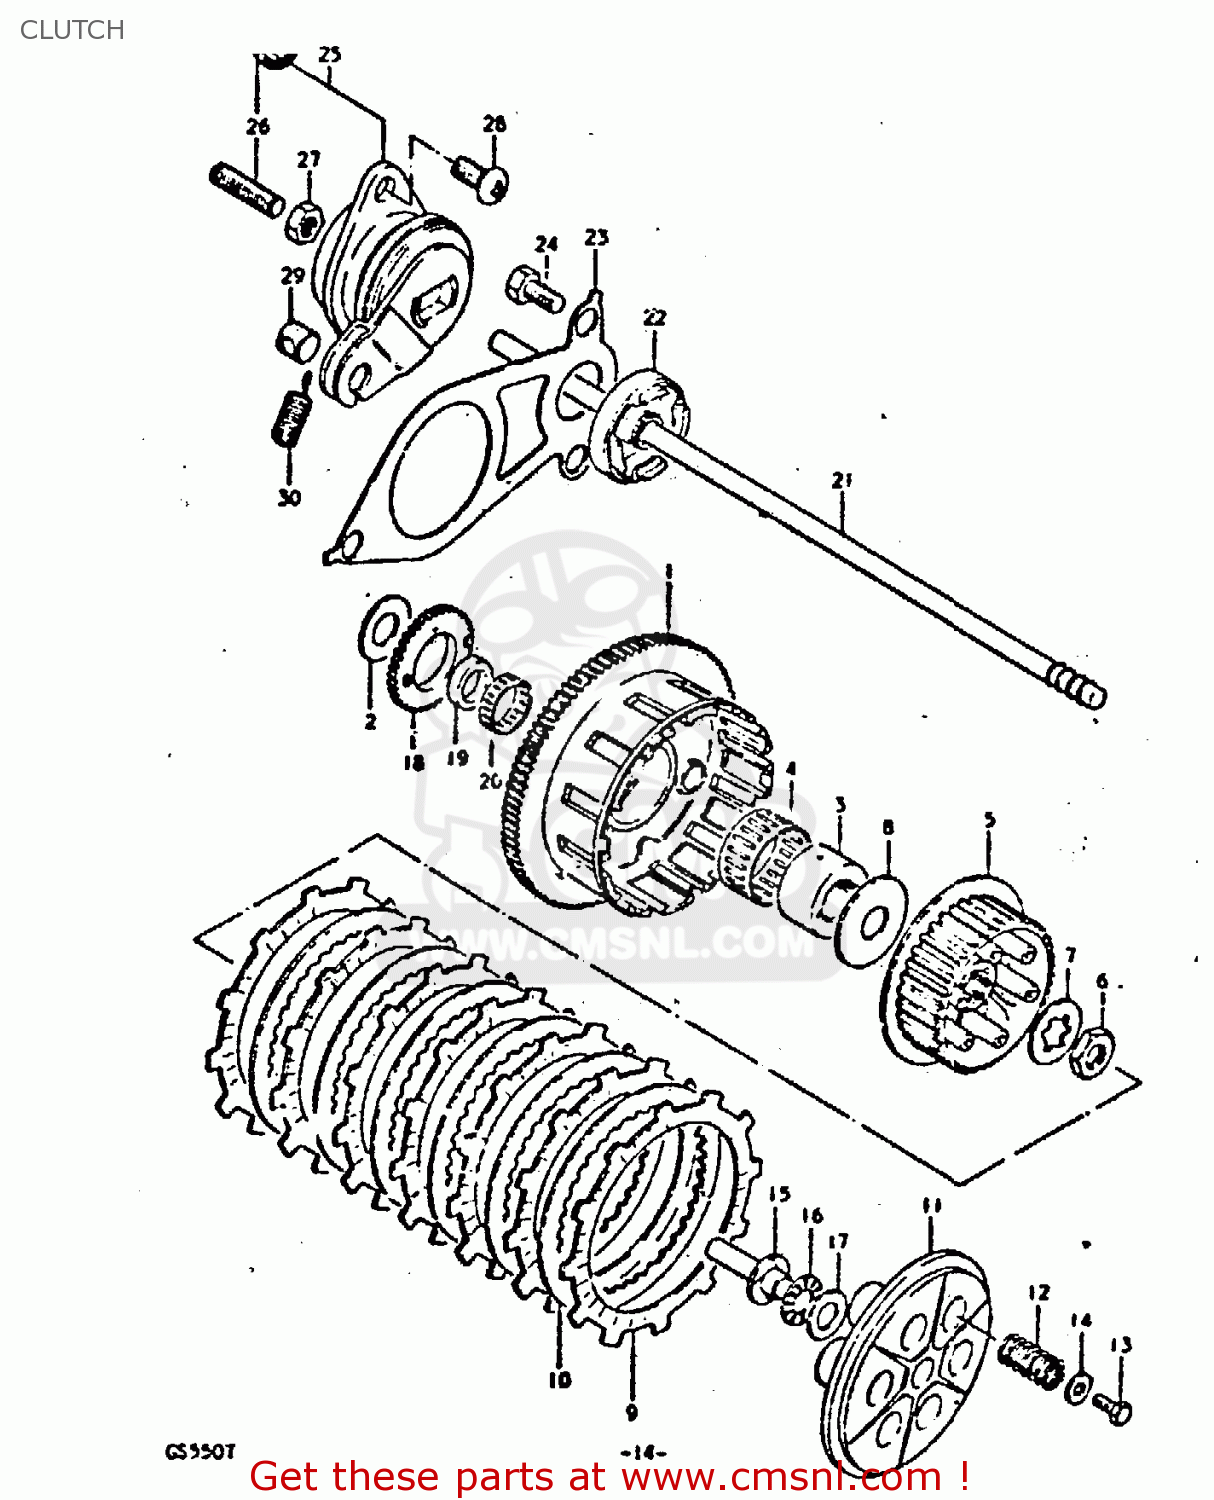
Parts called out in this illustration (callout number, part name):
1	GEAR ASSEMBLY,PRIMARY DRIVE NT:87
2	WASHER
3	SPACER,PRIMARY DRIVEN
4	BEARING
5	HUB,CLUTCH SLEEVE
6	NUT
7	WASHER,LOCK
8	WASHER(25X66X3.5)
9	PLATE,CLUTCH DRIVE (NAS)
10	PLATE,CLUTCH DRIVEN (NAS)
11	DISC,CLUTCH PRESSURE
12	SPRING
13	BOLT, UPPER
14	WASHER
15	PIECE,CLUTCH PUSH
16	BEARING(15X28X2)
17	WASHER
18	GEAR,ENG OIL PUMP DRIVE(NT:38)
19	SPACER,OIL PUMP DRIVE GEAR
20	BEARING(36X40X10)
21	ROD,CLUTCH PUSH
22	OIL SEAL
23	PLATE,CLUTCH PUSH ROD
24	BOLT
25	SCREW ASSEMBLY,CLUTCH RELEASE
26	SCREW
27	NUT 6MM
28	SCREW 6X12
29	PIECE,RELEASE ARM END
30	SPRING
